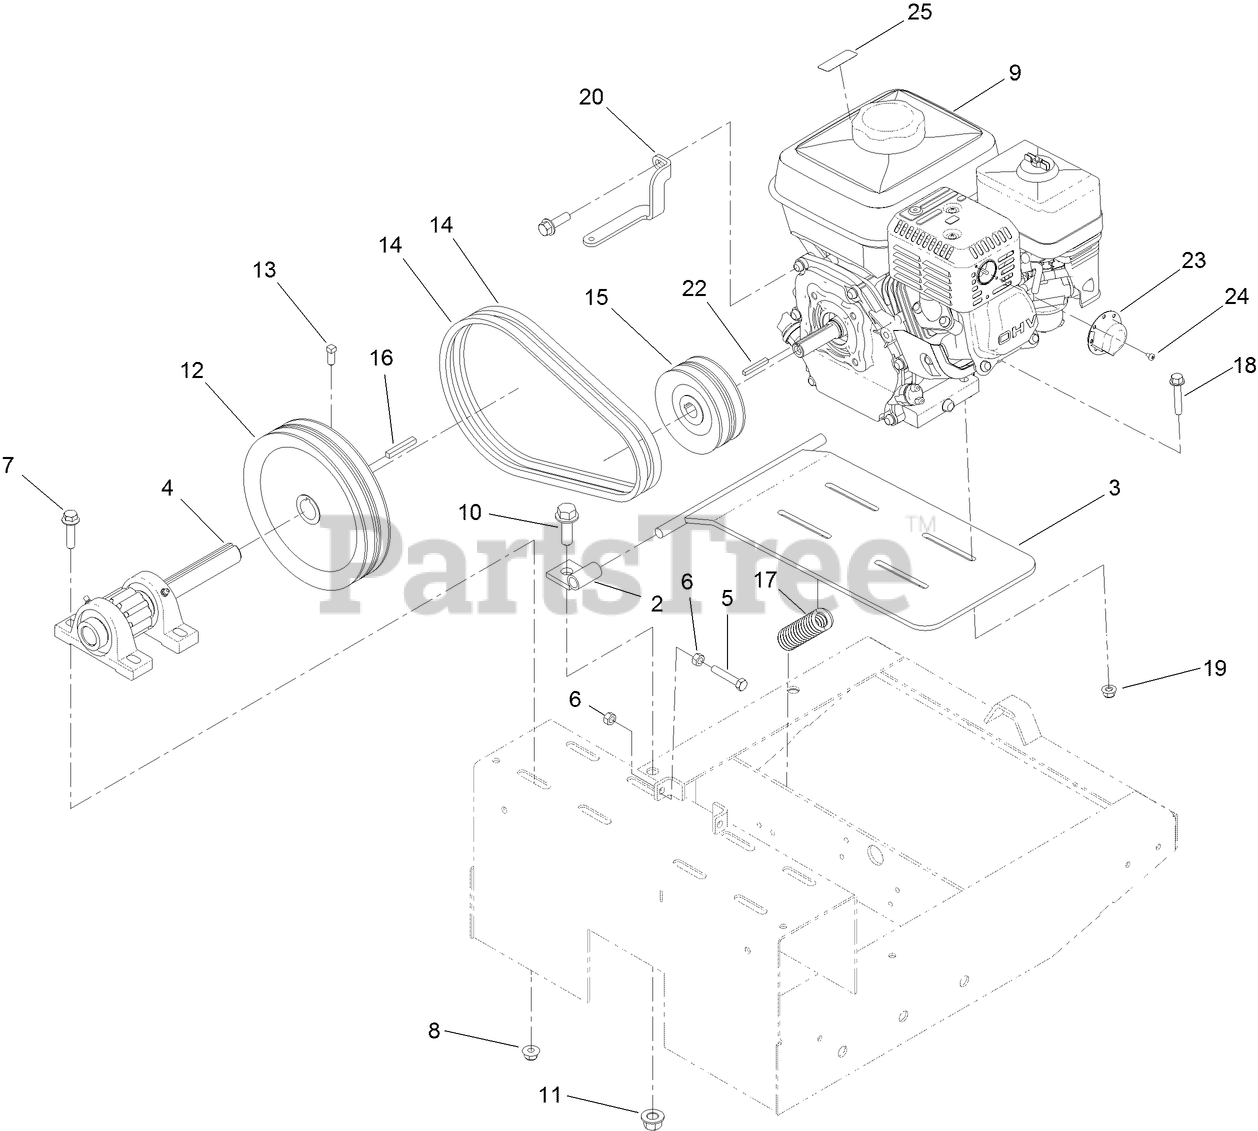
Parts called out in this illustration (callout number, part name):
2	MOUNT-MOTOR
3	BASE-MOTOR
4	PINION ASM
5	SCREW-HH
6	NUT-HEX
7	SCREW-HHF
8	NUT-HF, NI
9	ENGINE-HONDA, GX240
10	SCREW-HHF
11	NUT-LOCK
12	SHEAVE
13	SCREW-SET, SQH
14	BELT-V
15	SHEAVE
16	KEY-SQUARE
17	SPRING
18	SCREW-HHF
19	NUT-HF, NI
20	GUIDE-BELT
22	KEY-SQUARE
23	DEFLECTOR-EXHAUST, HONDA
24	SCREW-HWH
25	DECAL-WARNING, ETHANOL
